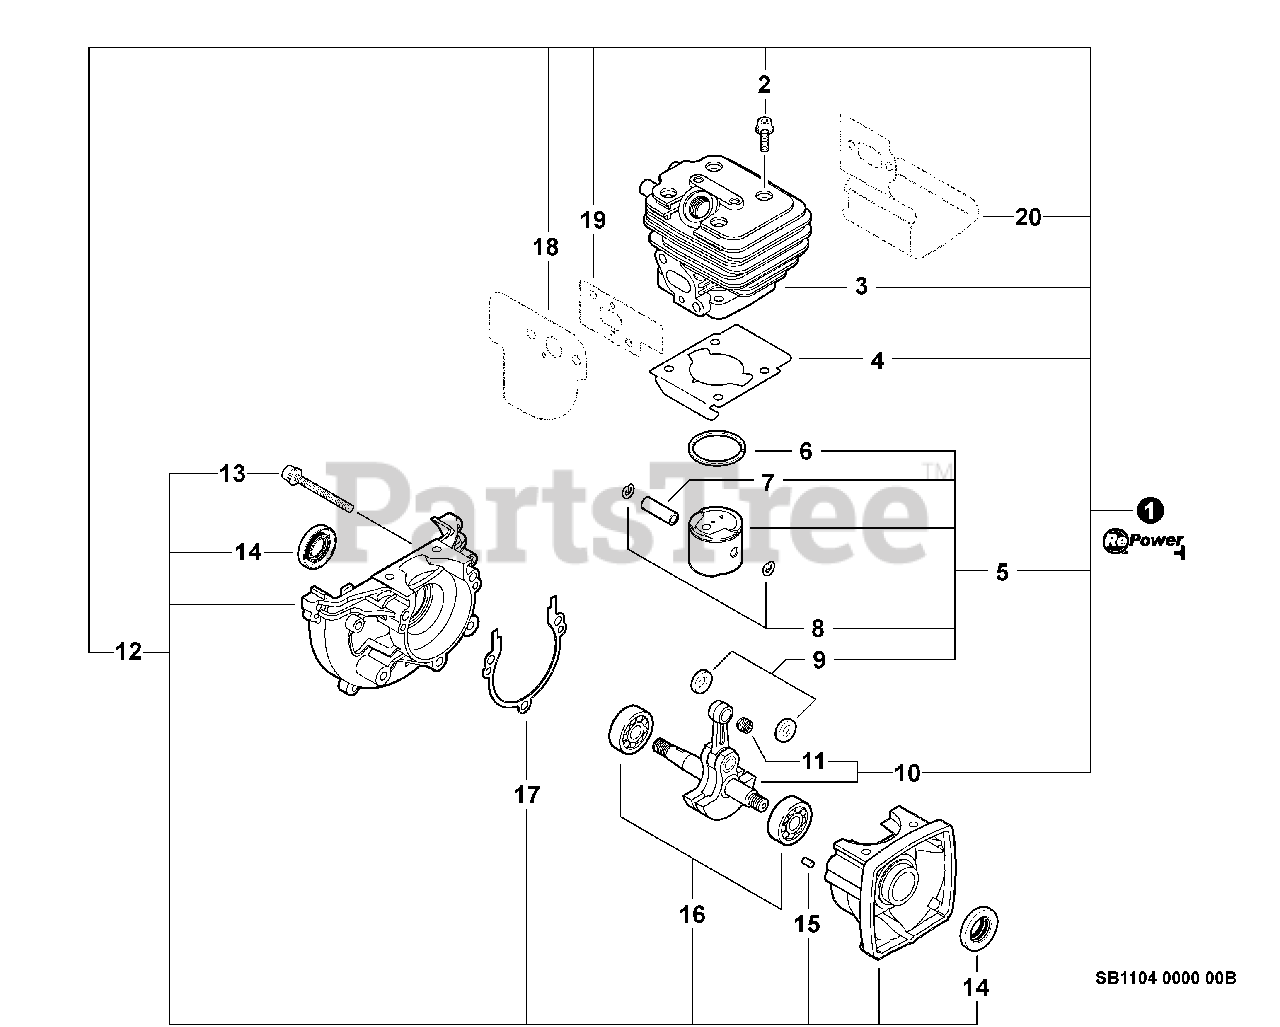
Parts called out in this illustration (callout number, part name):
1	SHORT BLOCK -- SB1104
2	SCREW - 5X25
3	CYLINDER
4	GASKET, CYLINDER
5	PISTON KIT
6	RING, PISTON
7	PIN, PISTON
8	RING, RETAINING
9	SPACER, PISTON
10	CRANKSHAFT ASSY
11	BEARING, NEEDLE - 8
12	CRANKCASE KIT
13	SCREW - 5X28
14	SEAL, OIL
15	PIN - LOCATING
16	BEARING, BALL - 6201
17	GASKET, CRANKCASE
18	GASKET, INTAKE
19	GASKET, INTAKE
20	SHIELD, EXHAUST
